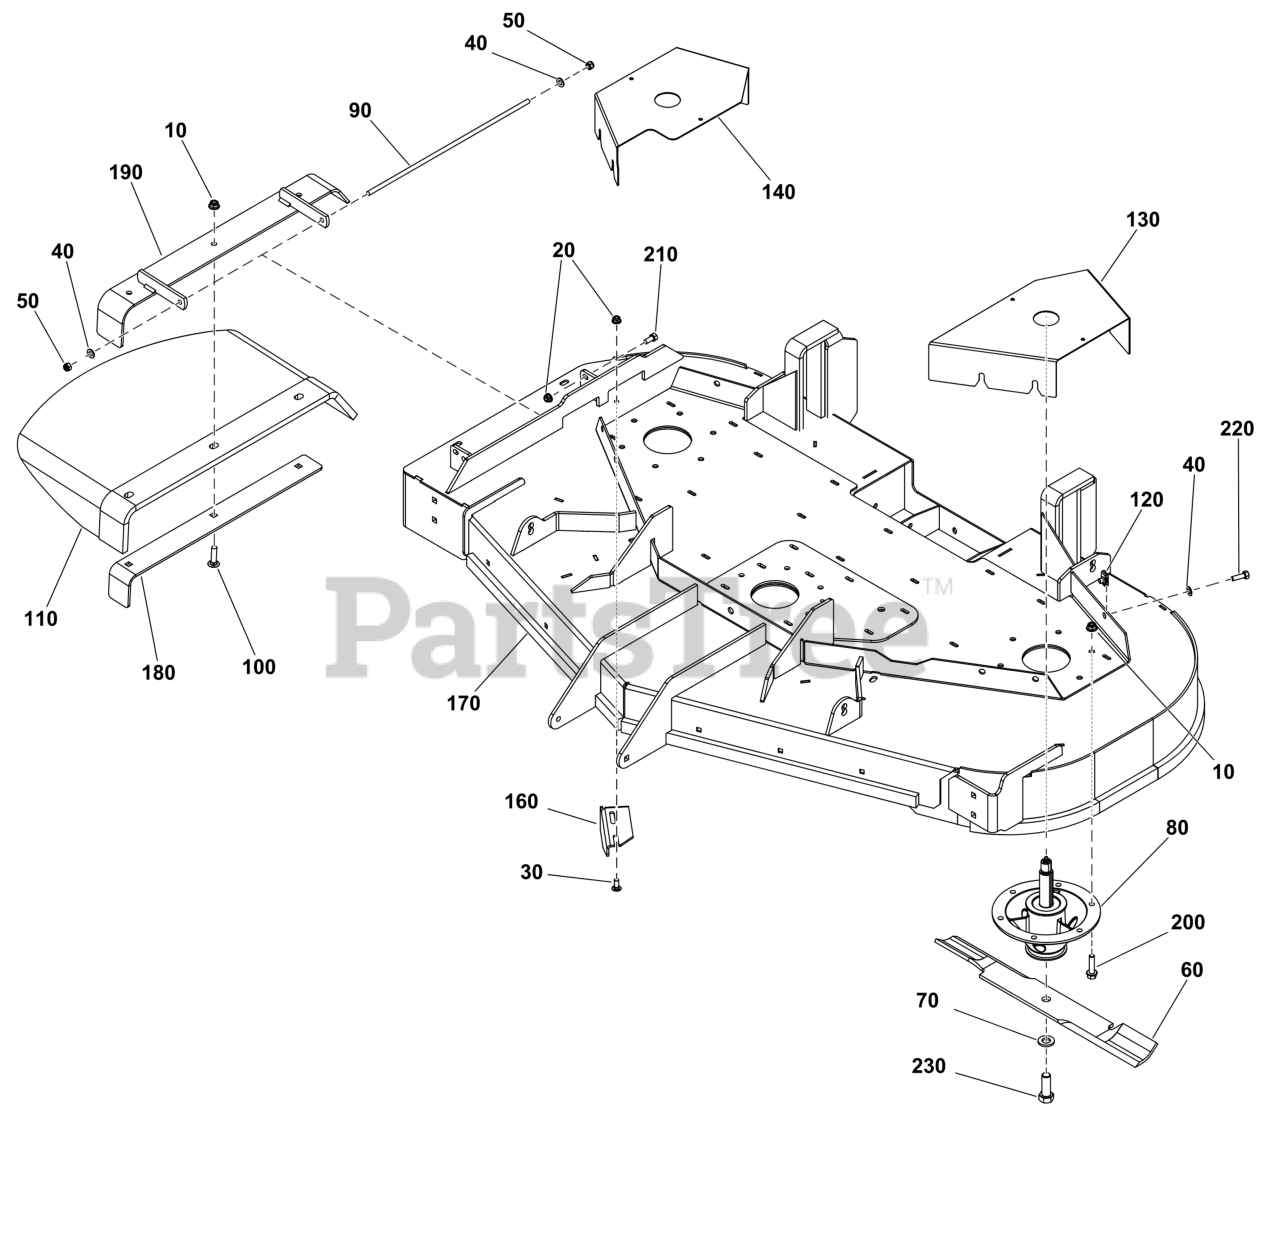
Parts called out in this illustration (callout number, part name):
10	NUT, 3/8-16 HEX NYLOCK
20	NUT
30	BOLT, 5/16-18 X 3/4",
40	WASHER
50	NUT, 5/16-24 HEX NYLO
60	BLADE SET, 61 DECK (3)
70	WASHER, 5/8" YZ
80	ASSEMBLY-SPINDLE
90	ROD
100	BOLT, 3/8-16 X 1-1/2
110	CHUTE, RUBBER DISCHARGE (5104442)
120	BODY CLIP, 5/16-18 X
130	PLATE, Guard, Left
140	PLATE, Guard, Right
160	DEFLECTOR
170	DECK SHELL W/ DECALS, SRSZ2-60
180	PLATE, SUPPORT
190	FRAME, Chute
210	BOLT, 5/16-18 X 3/4"
230	BOLT
